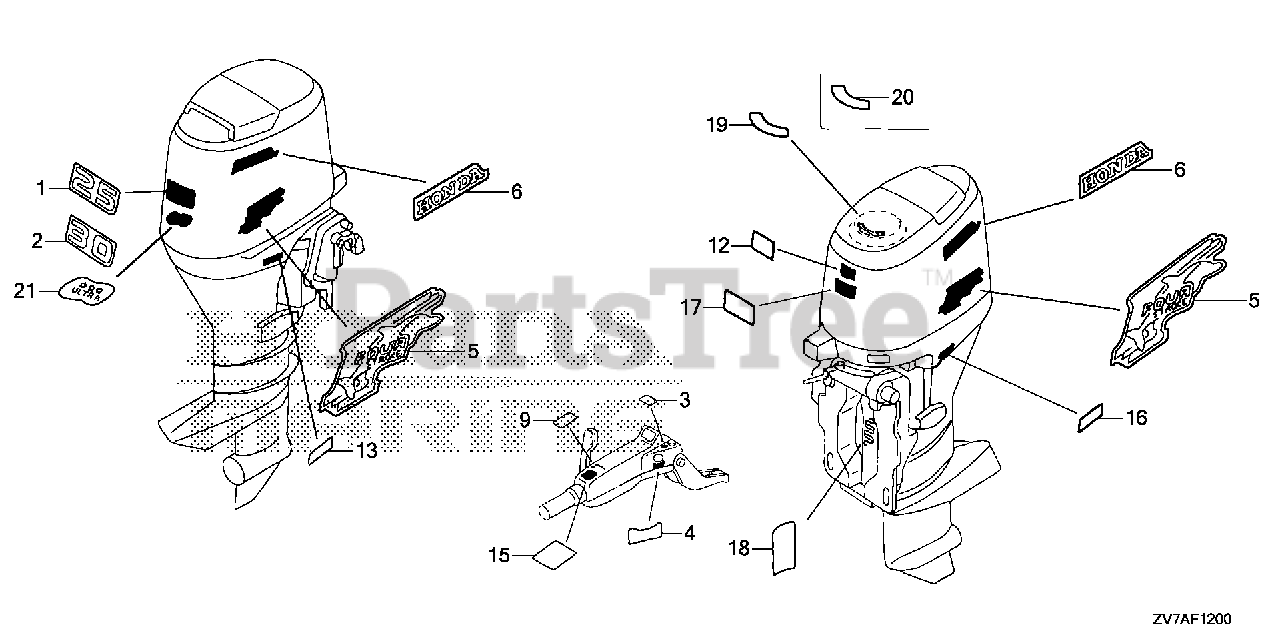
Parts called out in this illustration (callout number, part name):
1	MARK, RR. (25)
6	MARK, SIDE STRIPE
13	LABEL, OIL CAUTION (ENGLISH)
16	LABEL, STORING CAUTION (ENGLISH)
17	LABEL, WARNING OPERATOR (ENGLISH)
18	LABEL, ASSIST TILT CAUTION (ENGLISH)
19	MARK, EMERGENCY START (ENGLISH)
